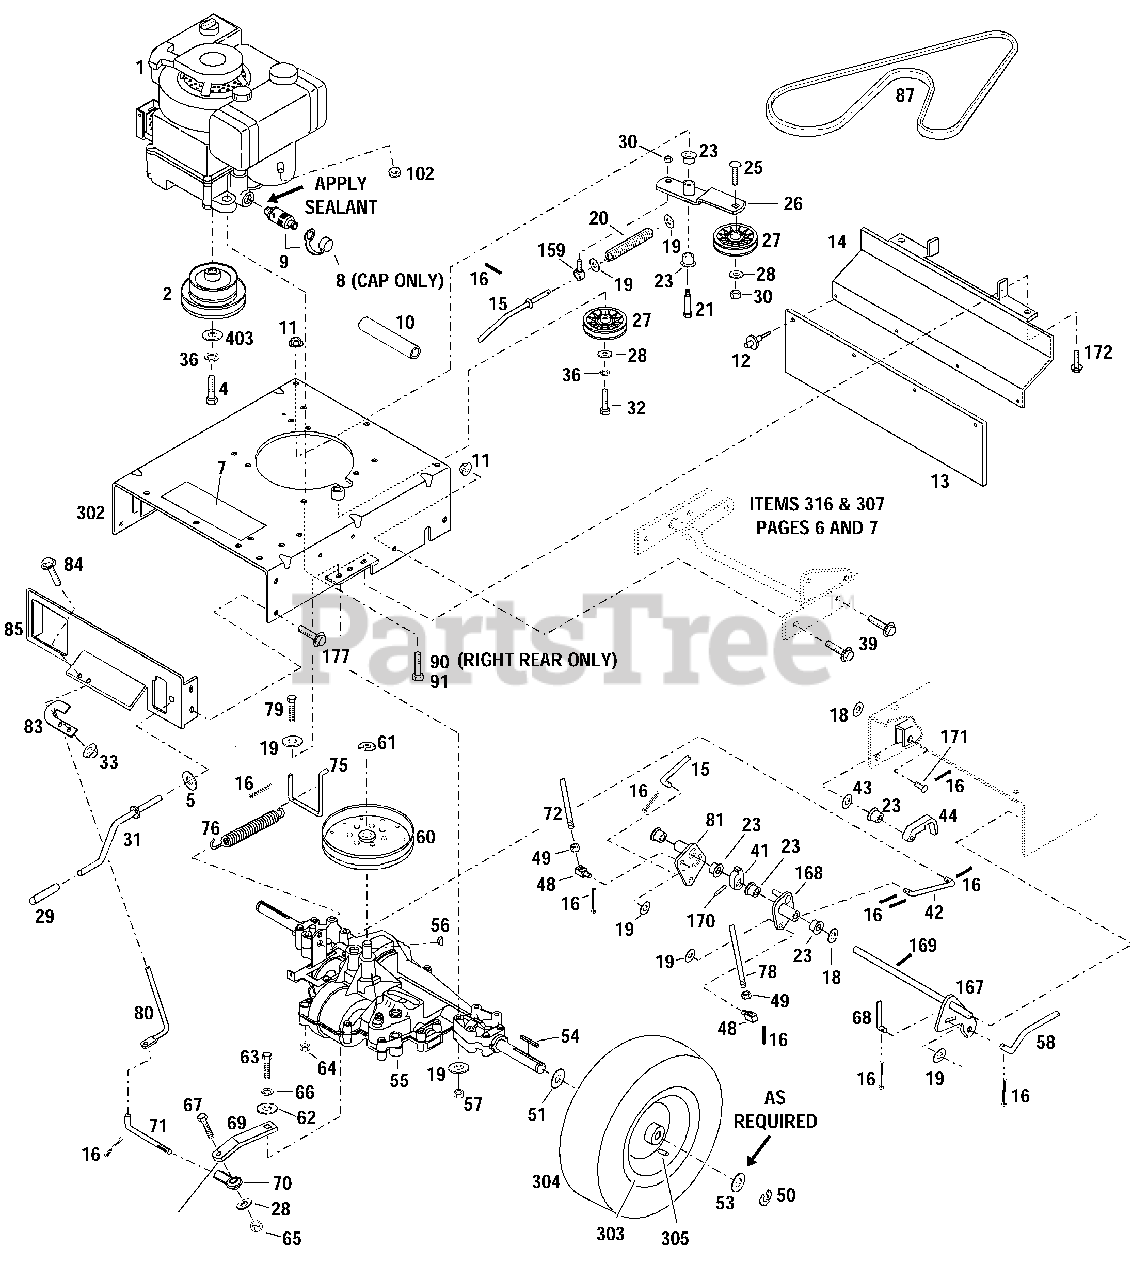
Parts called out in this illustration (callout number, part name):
1	Engine, 8 HP, Recoil Start
2	Engine Pulley
4	Bolt, 3/8-24 x 1-3/4 GR 8
5	Washer, Nylon
7	Warning Decal
8	Oil Valve Cap
9	Oil Valve
10	Oil Drain Hose
11	Flange Locknut, 3/8-16
12	Pop Rivet, 3/16
14	Flap Bracket
15	Lower Transmission Rod
16	Cotter Pin, 3/32 x 5/8
18	Flat Washer, 1/2
19	Flat Washer, 5/16
20	Compression Spring
21	Shoulder Bolt
23	Nyliner, 1/2
25	Carriage Bolt, 3/8-16 x 1-3/4
26	Idler Arm
27	Idler Pulley
28	Flat Washer, 3/8
29	Plastic Grip
30	Top Locknut, 3/8-16
31	Lift Crank Assembly
32	Bolt, 3/8-16 x 1-3/4
33	Flange Locknut, 1/4-20
36	Lock Washer, 3/8
39	Flange Lock Screw, 3/8-16 x 1
41	Interlock Cam
42	Lower Brake Rod
43	Washer, Flat 1/2
44	Interlock Latch
48	Swivel Block
49	Jam Nut, 5/16-18
50	Retaining Ring
51	Flat Washer
53	Special Washer
54	Square Key, 3/16 x 2-1/2
56	Woodruff Key, 3/16 x 3/4
57	Top Locknut, 5/16-18
58	Lower Blade Rod
60	Transaxle Pulley
61	Retaining Ring
62	Flat Washer, 1/4
63	Screw, 1/4-28 x 3/4
64	Flange Locknut, 5/16-18
65	Locknut, 3/8-16
66	Lock Washer, 1/4
67	Screw, 3/8 x 1-1/4
68	Upper Blade Rod
69	Transmission Arm
70	Ball Joint
71	Shift Link Rod
72	Upper Transmission Rod
75	Spring Attachment Rod
76	Extension Spring
78	Upper Brake Rod
79	Screw, 5/16-18 x 2-3/4
80	Shift Rod
81	Clutch Arm Pivot
83	Shift Rod Bracket
84	Flange Lock Screw, 1/4-20 x 1/2
90	Thread Forming Screw, 3/8-16 x 1-1/2
91	Thread Forming Screw, 3/8-16 x 1
102	Hex Nut, 1/4-20
159	Eye Bolt
167	Pivot Shaft Assembly
168	Brake Arm
169	Cotter Pin
170	Drive Pin, 5/32 x 1
171	Clevis Pin, 1/2 x 1-1/4
172	Screw, 5/16-18 x 3/4
177	Flange Screw, 5/16-18 x 3/4
302	Frame Weldment Ass'y
303	Wheel Rim
304	Tire
305	Valve Stem
400	Loctite 242, 0.02 oz. Tube
403	Flat Washer, 3/8
